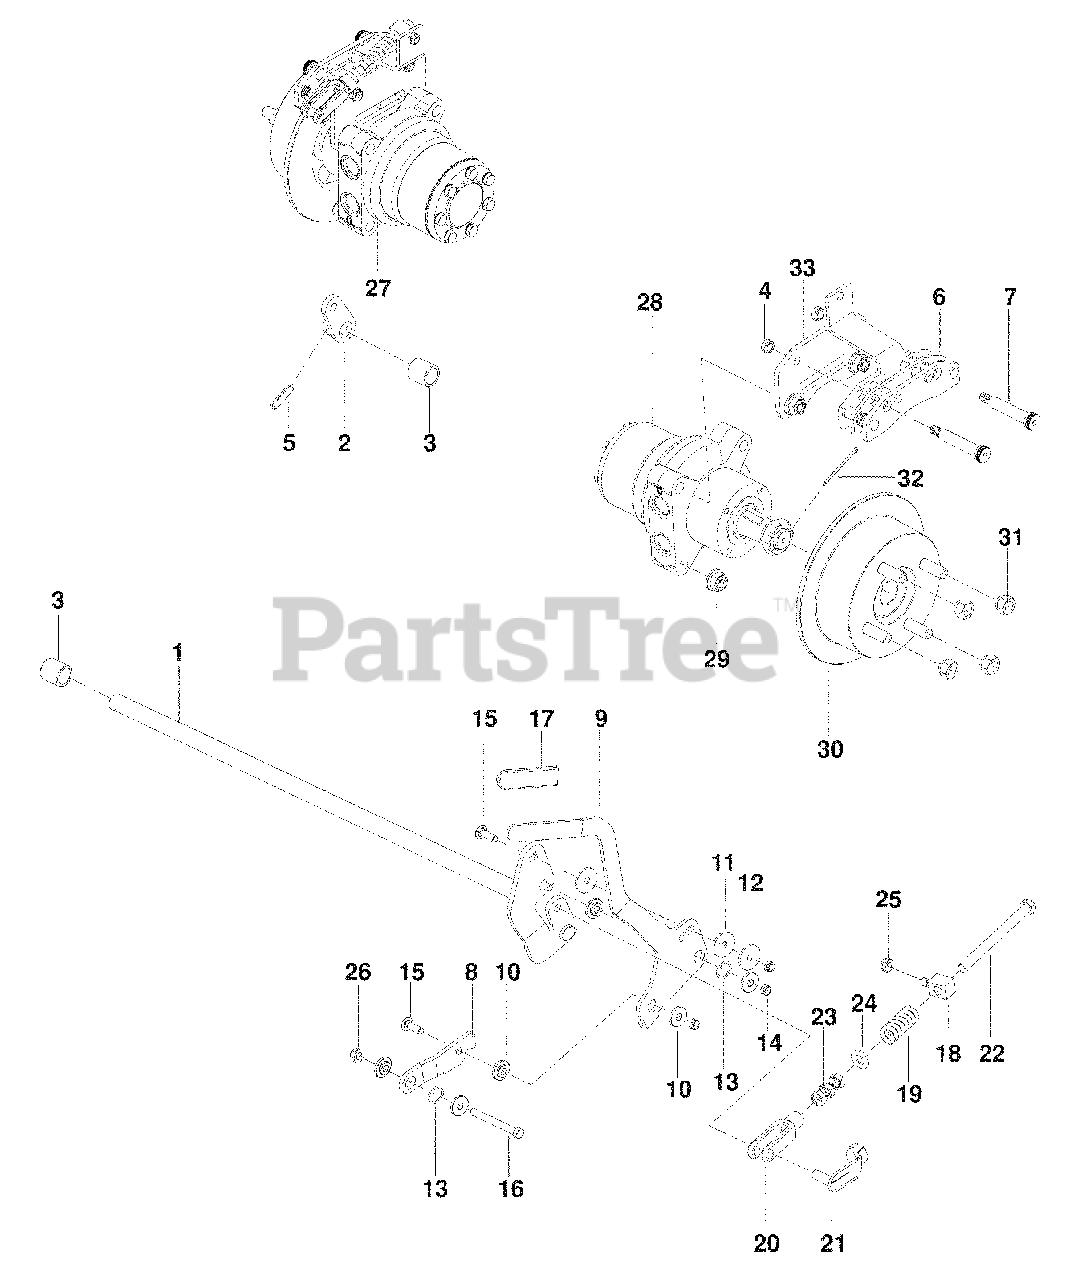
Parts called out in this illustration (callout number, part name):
1	SHAFT, BRAKE
2	ARM, RT BRAKE
3	BUSHING, SLEEVE ¾ x 1
4	NUT 3/8-16 HEX JAM NYLOC
5	ROLL PIN 5/16" DIA.
7	BOLT ½ x 2¼, 3/8-16 SHLDR
8	LINK, FOLLOWER
9	LEVER, BRAKE
10	BUSHING, BRAKE
11	WASHER, FRICTION
12	WASHER, CONE
13	WASHER, WAVE
14	NUT 3/8-16 HEX JAM NYLOC
15	BOLT 3/8-16 x 1¼ RD HD
16	BOLT 3/8-16 x 3¼ HEX NYLOC
17	GRIP, LEVER
18	SWIVEL, BRAKE
21	PIN 3/8 CLEVIS SPRING
22	BOLT 3/8-24 x 4½ HEX NYL
23	NUT 3/8-24 HEX JAM
24	WASHER 3/8 SAE FLT
25	NUT 5/16-18 HEX NYLOC INS
26	NUT 3/8-16 HEX FLG NYLOC
29	NUT ½-13 HEX FLG NYLOC
30	HUB, DISC BRAKE, w/ STUDS
31	LUG NUT ½
32	COTTER PIN 1/8 x 2
33	PLATE, CALIPER
